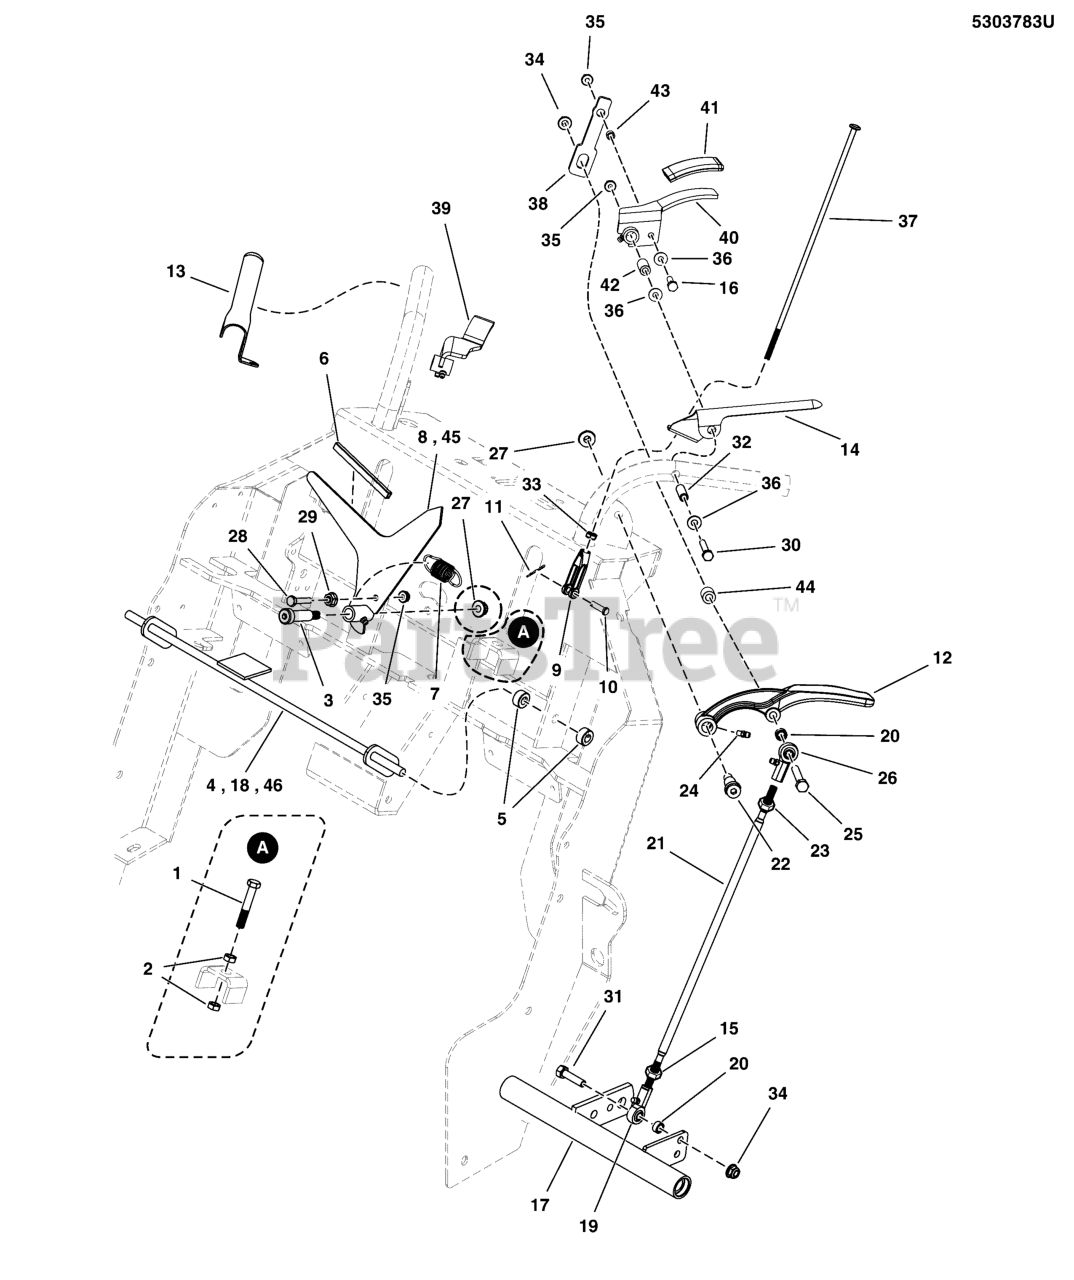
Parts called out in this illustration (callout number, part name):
1	BOLT, 1/2-20 X 2-1/2, FLT
2	NUT, 1/2-20 HEX JAM
3	BOLT-3/8-16 x 1-1/2, 1/2 SHOULDER
4	WELD, OPC ROD, WALK - BLK
5	COLLAR, 3/8 SET
6	U-CHANNEL, RPVC #6236 X 4"
7	SPRING, EXT, 0.525 X 0.058 X 2.250 SS
8	SENSOR, Speed
10	PIN, CLEVIS, 1/4 X 7/8, PLATED
11	PIN, COTTER, 1/8 X 1-1/4
12	HANDLE, REVERSING - BLK
15	NUT, 5/16-24 HEX, LH
16	BOLT, 1/4-20 X 1" GD5 CZ
17	SEE MOTION CONTROL GROUP - FORWARD SPEED CONTROL LEVER AND SPRING ASSEMBLIES
18	WELD, OPC ROD, WALK - BLK
19	BALL JOINT 5/16-24 LH FEMALE BRONZE RACE
20	SPACER, .33 X .50 X .25, CZ
21	ROD, 5/16-24 X 15.48, LH-RH, CZ
22	BOLT, 3/8-16 X 1/2, 1.00 SHOULDER, CZ
23	NUT, 5/16-24 HEX
24	GREASE FITTING, 1/4-28 STRAIGHT
25	BOLT, 5/16-18 X 3" GD5
26	BALL JOINT 5/16-24 RH FEMALE BRONZE RACE
27	NUT, 3/8-16 HEX NYLOCK FLANGE
28	BOLT, 1/4-20 X 1-1/4, GD5
29	NUT, 1/4-20 HEX SERR. FLANGE
30	BOLT, 1/4-20 X 3" GD5
31	BOLT, 5/16-18 X 1-1/4, GD5
32	SPACER, .26 X .38 X 1.25, CZ
33	HN, 1/4F GR5 YZ
34	NUT, 5/16-18 HEX NYLOCK FLANGE
35	NUT, 1/4-20 HEX NYLOCK FLANGE
36	WASHER, 1/4 SAE
37	ROD, OPC LINK, SNP PRO WB
38	LINK, THUMB CONTROL - BLACK
39	WELD, THUMB CONTROL, RH - BLK
40	WELD, THUMB CONTROL, LH - BLK
41	GRIM, FOAM, 1/8" X 1.13" X 2.75"
42	SLEEVE CRUISE CONTROL, ROLLER
43	SPACER, .265 X .375 X .250, CZ
44	SPACER, .33 X .625 X .88, STEP, CZ
45	WELD, SPEED INDICATOR, LOCK OUT - BLK
46	WELD, OPC ROD, WALKBEHIND - BLK
